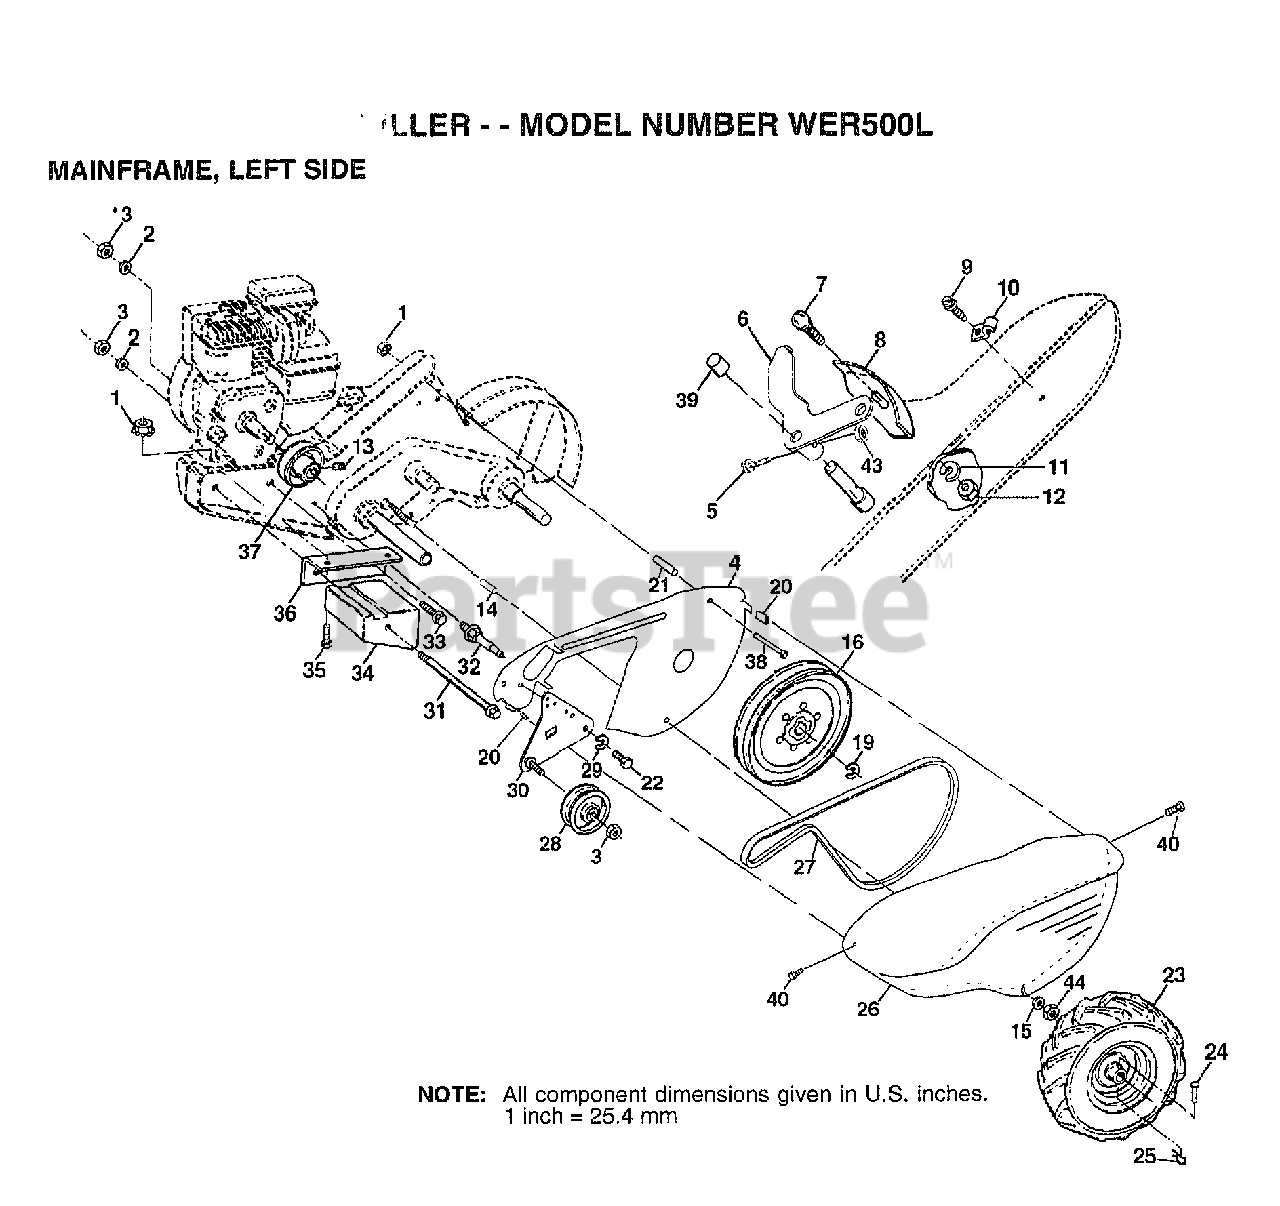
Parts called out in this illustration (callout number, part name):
2	LOCKWASHER
3	NUT.HEX.3/8-16UNC
4	SHIELD.INNER.BELT
5	"SCREW-LEVER,SHI"
6	LEVER ASM CRT
7	BOLT
8	PANEL TI
10	CONDIUT CLIP T
11	LOCKWASHER
13	SET SCREW
14	SPACER-SPLIT
15	WASHER
16	SHEAVE.TRANS.
20	NUT J CLIP #8
21	SPACER CRT
22	BOLT.FIN.HX.5/16-24X1/2
23	TIRE.CHV.13X5.0-6
24	RIVET.DRILL.1.75
25	RETAINER M
26	GUARD.BELT
27	BELT-V
28	PULLEY-IDLER TI
29	KLIP RING
30	BRACKET ASM IDLER
31	BOLT CRT
32	SHIFT ARM CRT
33	BOLT
34	COUNTERWEIGHT CRT
35	BOLT.HEX.5/16-1.5
36	BRACKET LH CRT
37	ENGINE PULLEY
39	CAP PLUNGER BLACK
40	SCREW HX WSH.HD#8-18X1/2
43	LOCKNUT
44	NUT
